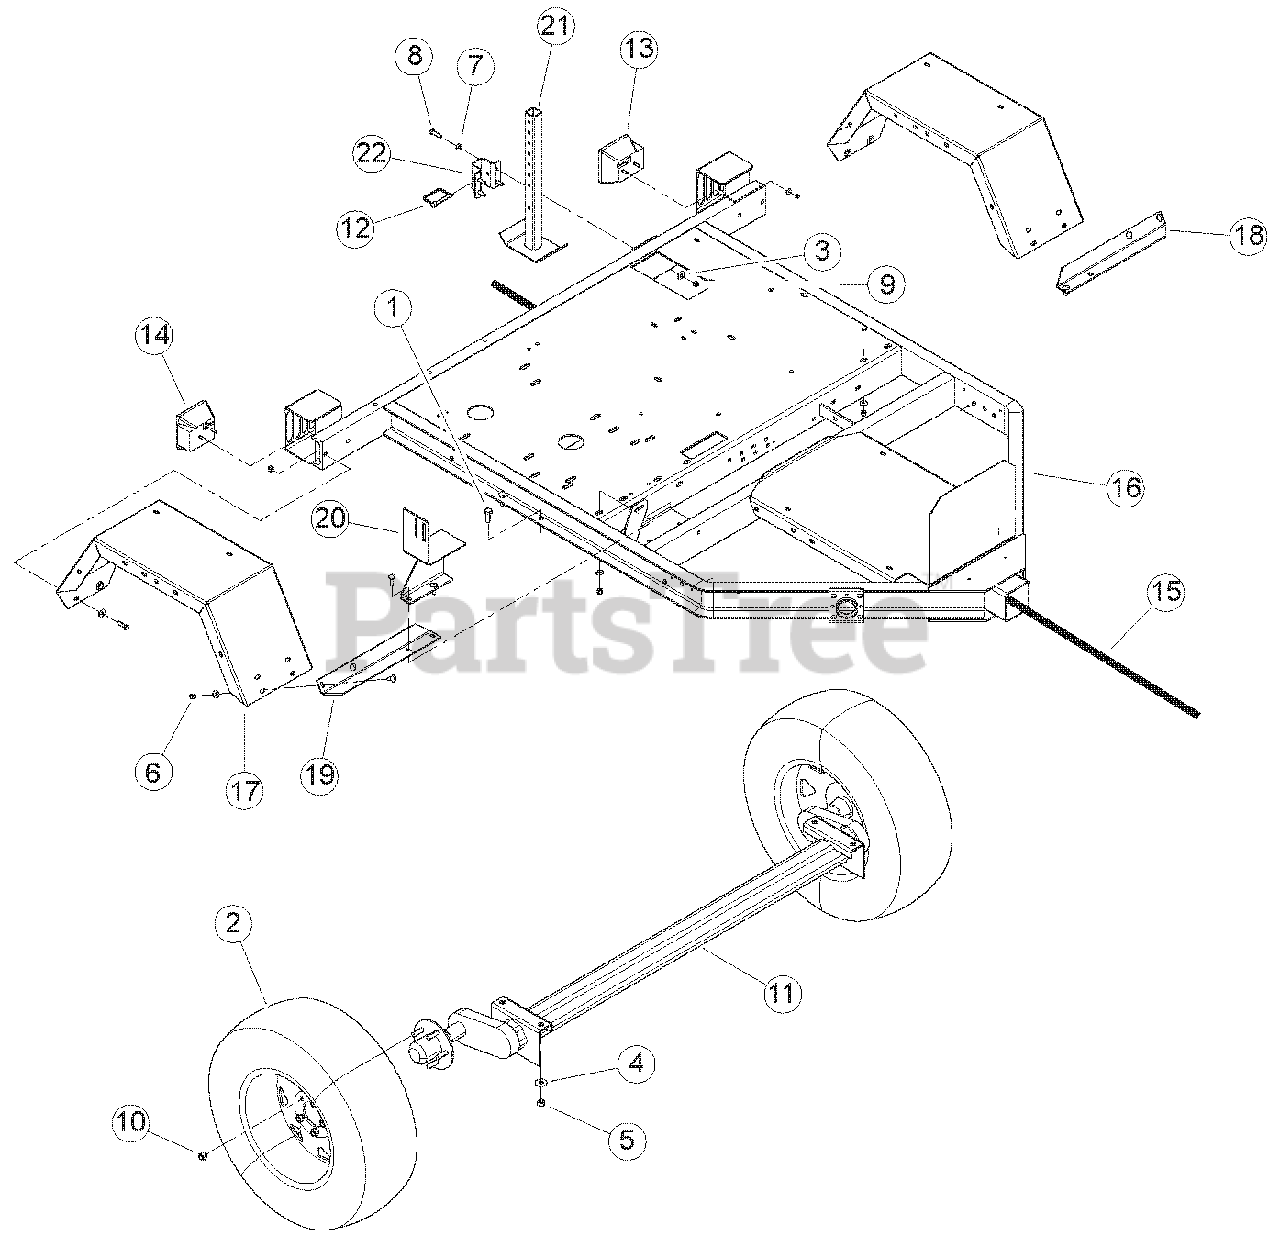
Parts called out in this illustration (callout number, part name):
1	BOLT, 1/2 X 2-1/4 HEX HD GR5 ZP
2	ASSEMBLY, 15 IN. TIRE & WHEEL
3	WASHER, 3/8 FLAT ZP
4	WASHER, 1/2 FLAT ZP
5	NUT, 1/2 CENTERLOCK GRB ZP
6	BOLT, 3/8 X 1 CRG GR5 NC ZP
7	WASHER, 3/8 SAE FLAT ZP
8	BOLT, 3/8 X 1-1/4 HEX HD GR5 ZP
9	NUT, 3/8 NE NYLOCK ZP
10	NUT, 1/2 -20 WHEEL
11	AXLE, 3000 LB. TORSION
12	PIN, 3/8 X 2-3/4 SNAP
13	LIGHT, LH TAIL
14	LIGHT, RH TAIL
15	HARNESS, TRAILER LIGHT
16	WELDMENT, CHIPPER TRAILER
17	FENDER, HEAVY DUTY
18	ANGLE, FENDER MOUNT LH
19	ANGLE, FENDER MOUNT RH
20	WELDMENT, BELT GUIDE
21	WELDMENT, REAR STABILIZER
22	GUIDE, TRAILER SUPPORT
